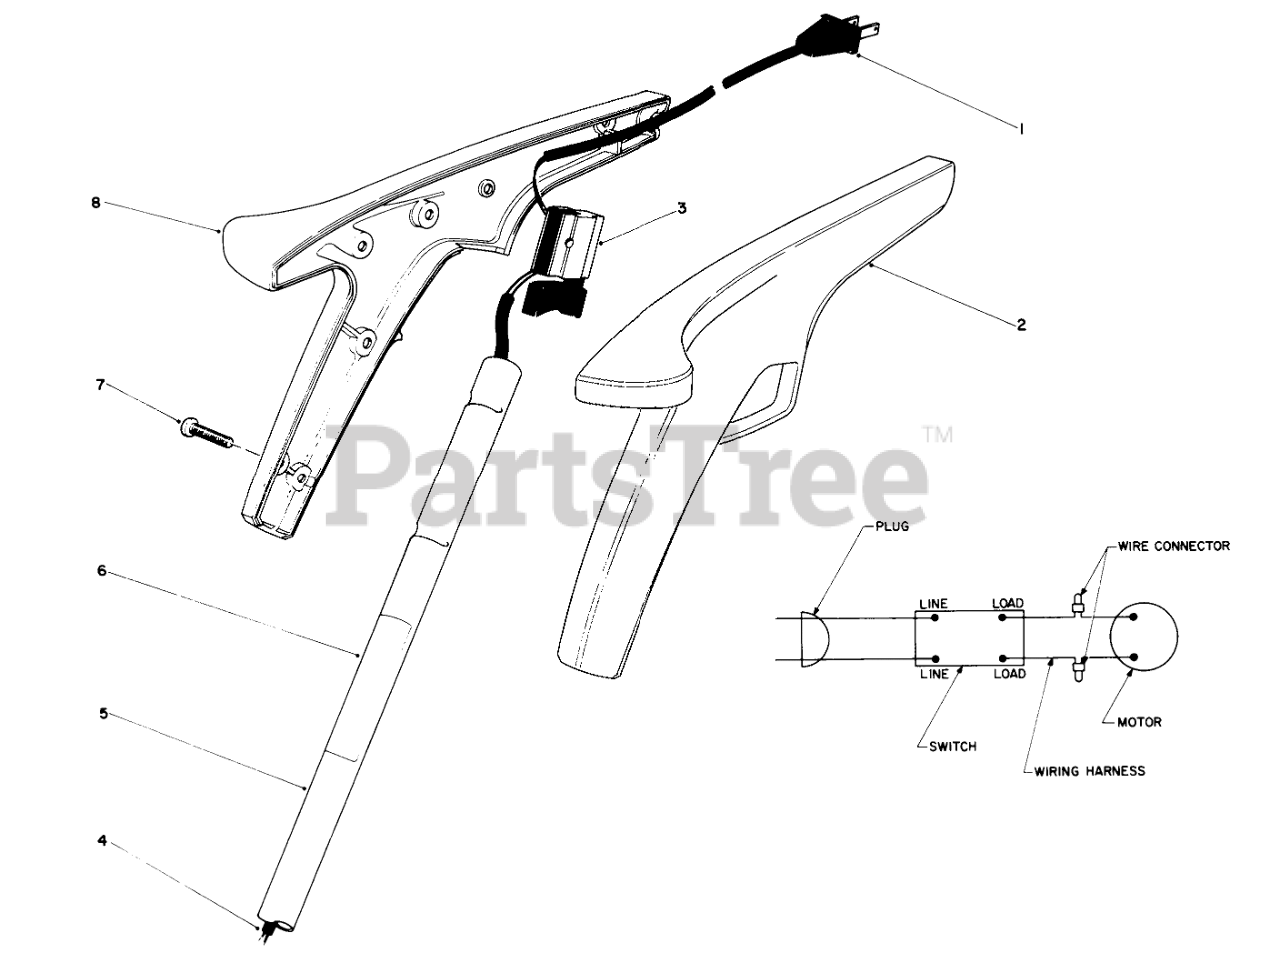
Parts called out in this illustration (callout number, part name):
1	Power Cord
2	LH HANDLE GRIP
3	SWITCH SINGLE SPEED
4	WIRING HARNESS
6	REP. SERIAL PLT
7	#8 X .625" PHILPS PAN H
8	Grip-Right Hand
